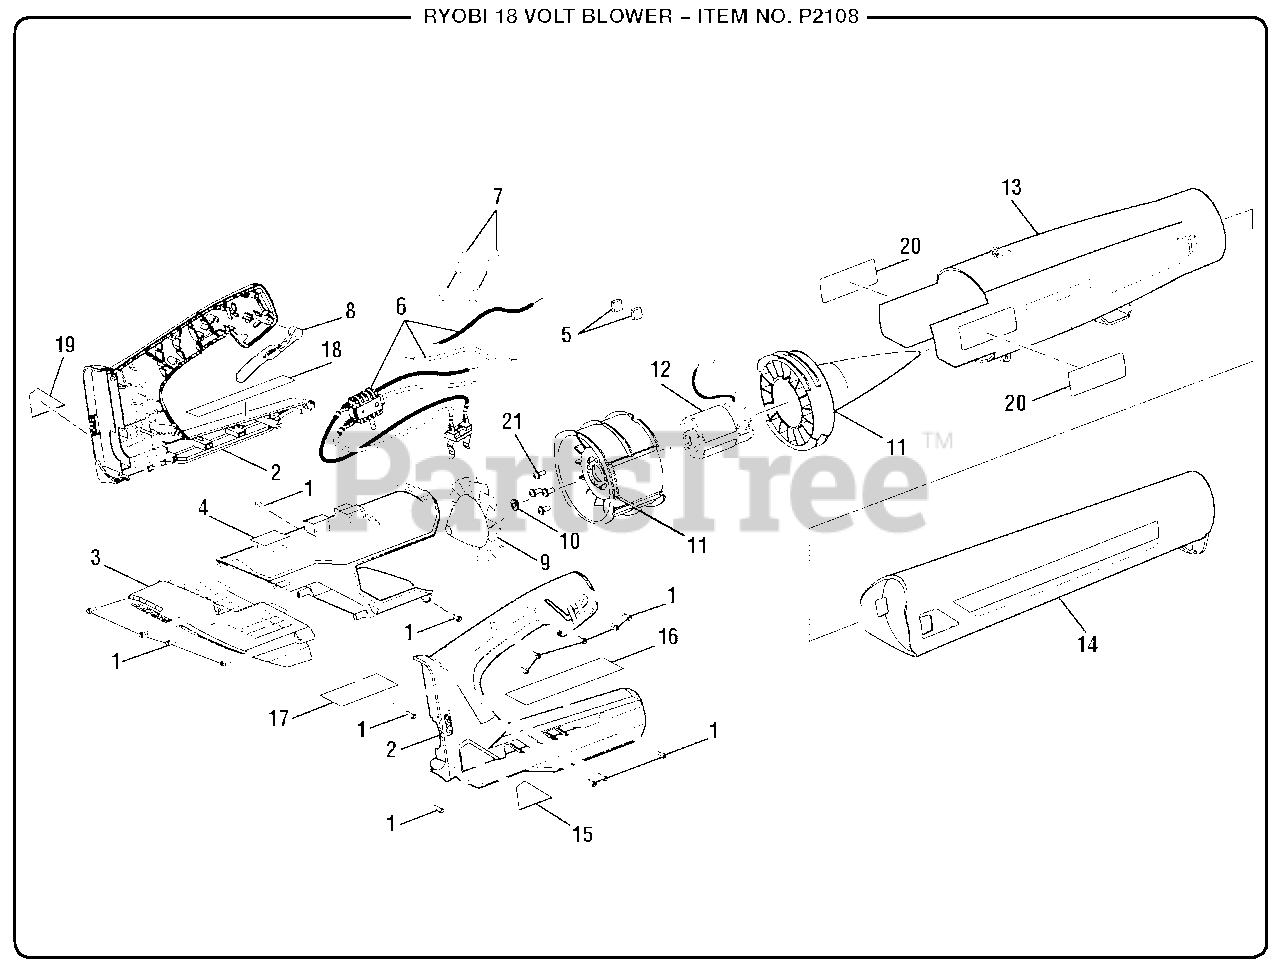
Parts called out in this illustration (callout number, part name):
1	Screw (M4 x 14 mm, T15 Torx Pan Hd.)
2	Handle Assembly
3	Inlet Guard
4	Inlet Housing Assembly
5	Rubber Block
6	Switch and Contact Plate Assembly
7	Wire Connector
8	Trigger Assembly (Variable Speed)
9	Fan Blade
11	Tail Cone Assembly
13	Blower Housing Outlet Assembly
14	Blower Tube
15	18 Volt Logo Label (Right)
16	Warning Label
17	Data Label
18	Warning Icon Label
19	18 Volt Logo Label (Left)
20	Logo Label (Ryobi)
21	Screw w/Washer (M5 x 11 mm, Pan Hd.)
